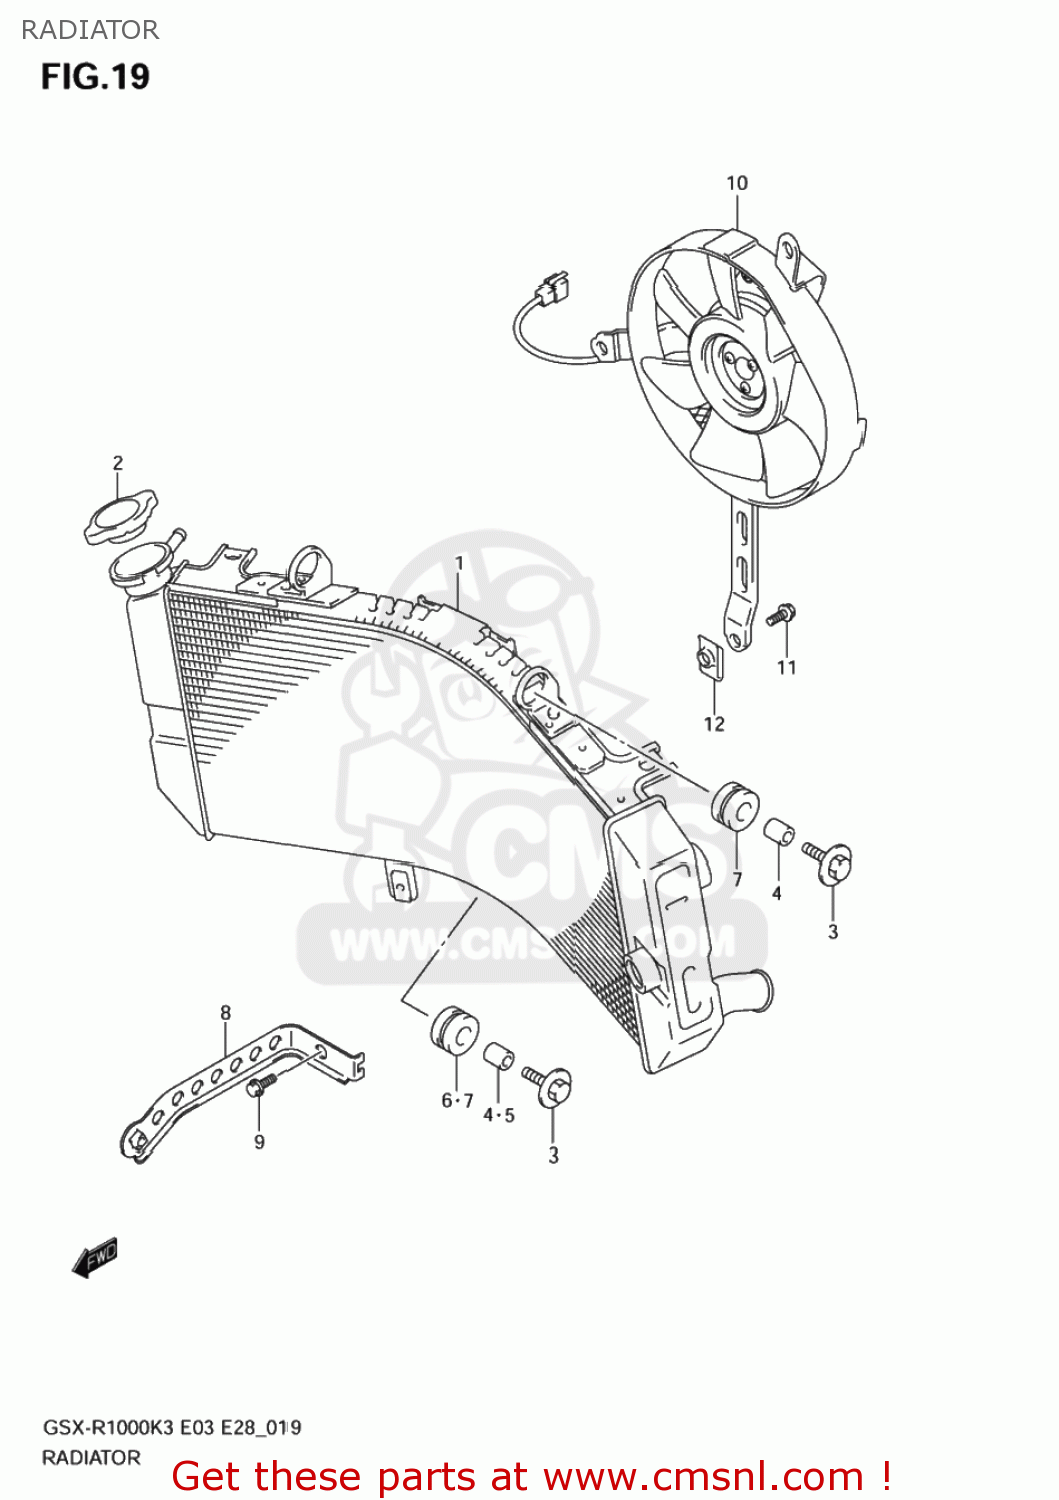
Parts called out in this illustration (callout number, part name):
1	RADIATOR ASSY,WATER
2	CAP COMP,RADIATOR
3	BOLT(6X25)
4	SPACER(6.5X10X12)
5	SPACER(6.5X10X14)
6	CUSHION
7	CUSHION
8	BRACKET,RADIATOR
9	BOLT
10	FAN ASSY,RADIATOR
11	BOLT,FAN ASSY
12	NUT,FAN ASSY
